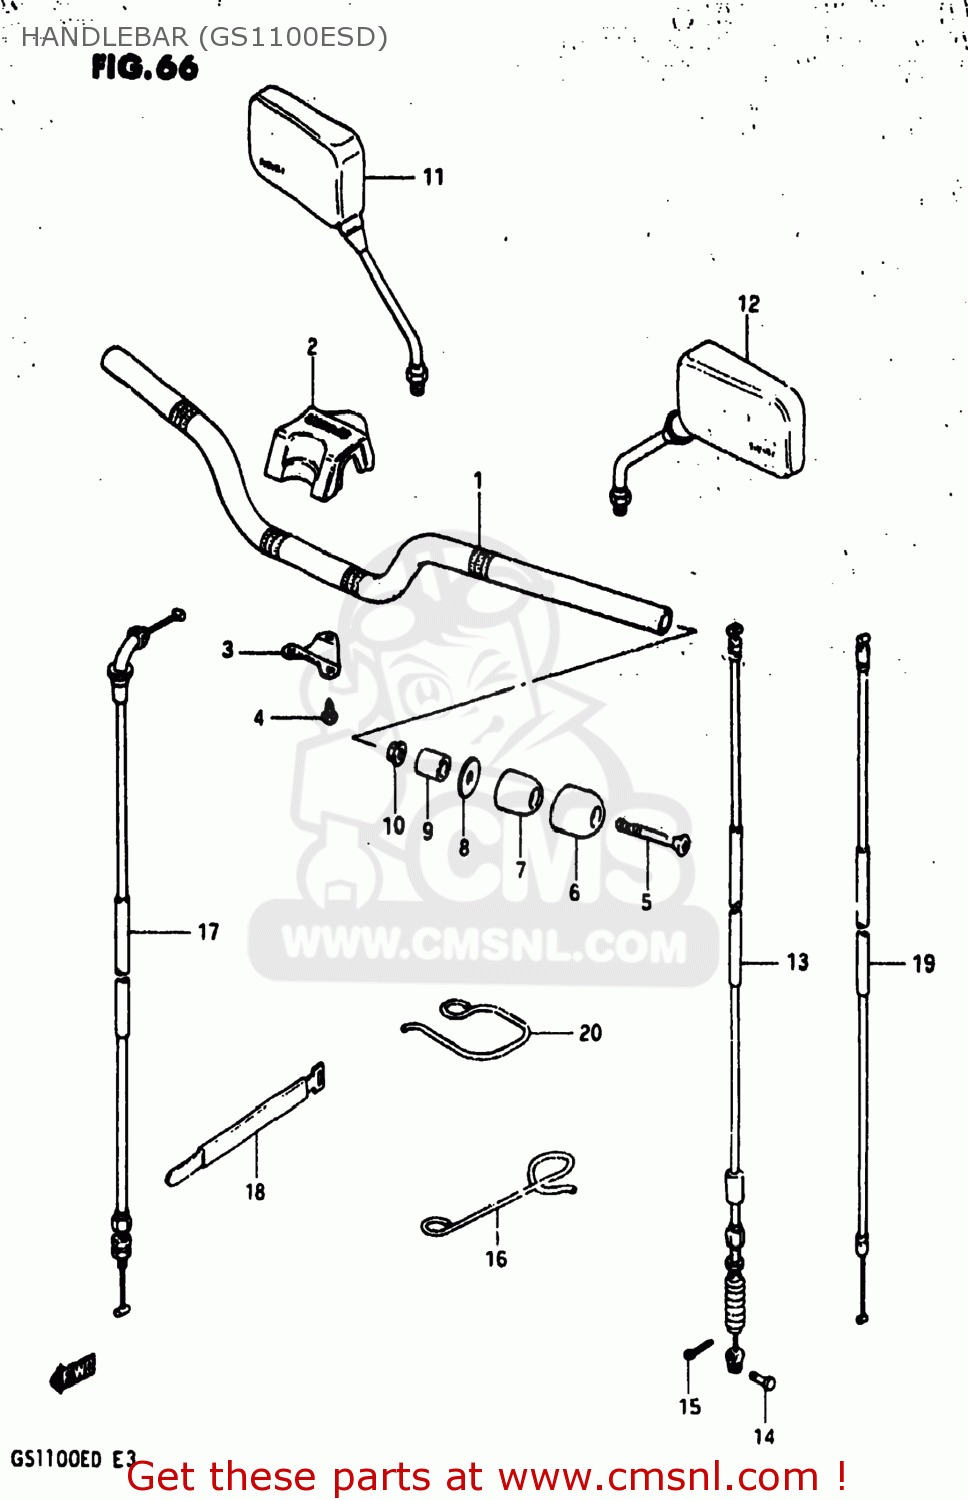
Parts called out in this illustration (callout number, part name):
1	HANDLEBAR
2	COVER,STEERING HEAD
3	BRACKET,STEERING HEAD
4	SCREW
5	SCREW (FLAT TYPE)
6	CAP,BALANCER
7	BALANCER,HANDLEBAR
8	SPACER,BALANCER
9	EXPANDER,HANDLE BALANCER
10	NUT
11	MIRROR ASSEMBLY,REAR VIEW
12	MIRROR ASSEMBLY,REAR VIEW
13	CABLE ASSEMBLY,CLUTCH
14	PIN(L:15)
15	PIN
16	GUIDE,CLUTCH CABLE
17	CABLE ASSEMBLY,THROTTLE
18	CLAMP
19	CABLE ASSEMBLY,STARTER
20	GUIDE,CABLE/HARNESS
